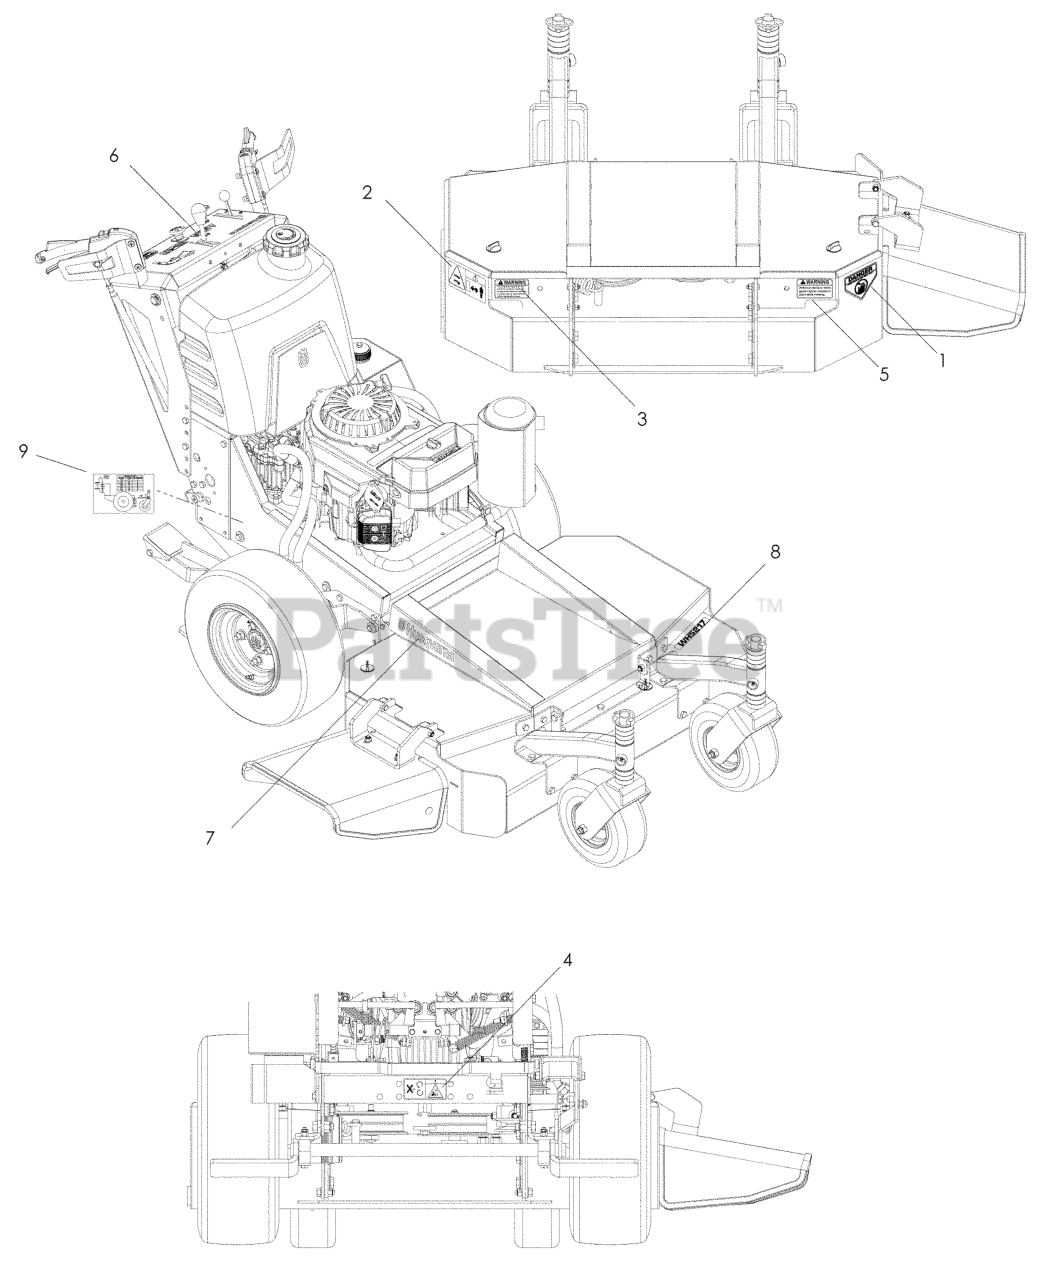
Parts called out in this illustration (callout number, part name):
1	DECAL, CPSC
2	DECAL, EURO SEVERING
3	DECAL, PROP. 65
4	DECAL, BELT DRIVE
5	DECAL, CAUTION
6	DECAL, INST PANEL
7	DECAL.HOOD.LOGO.ORANGE.HUSQVAR
8	DECAL, CROWN H 70MM
9	DECAL, HEIGHT OF CUT
10	DECAL, WH5217
